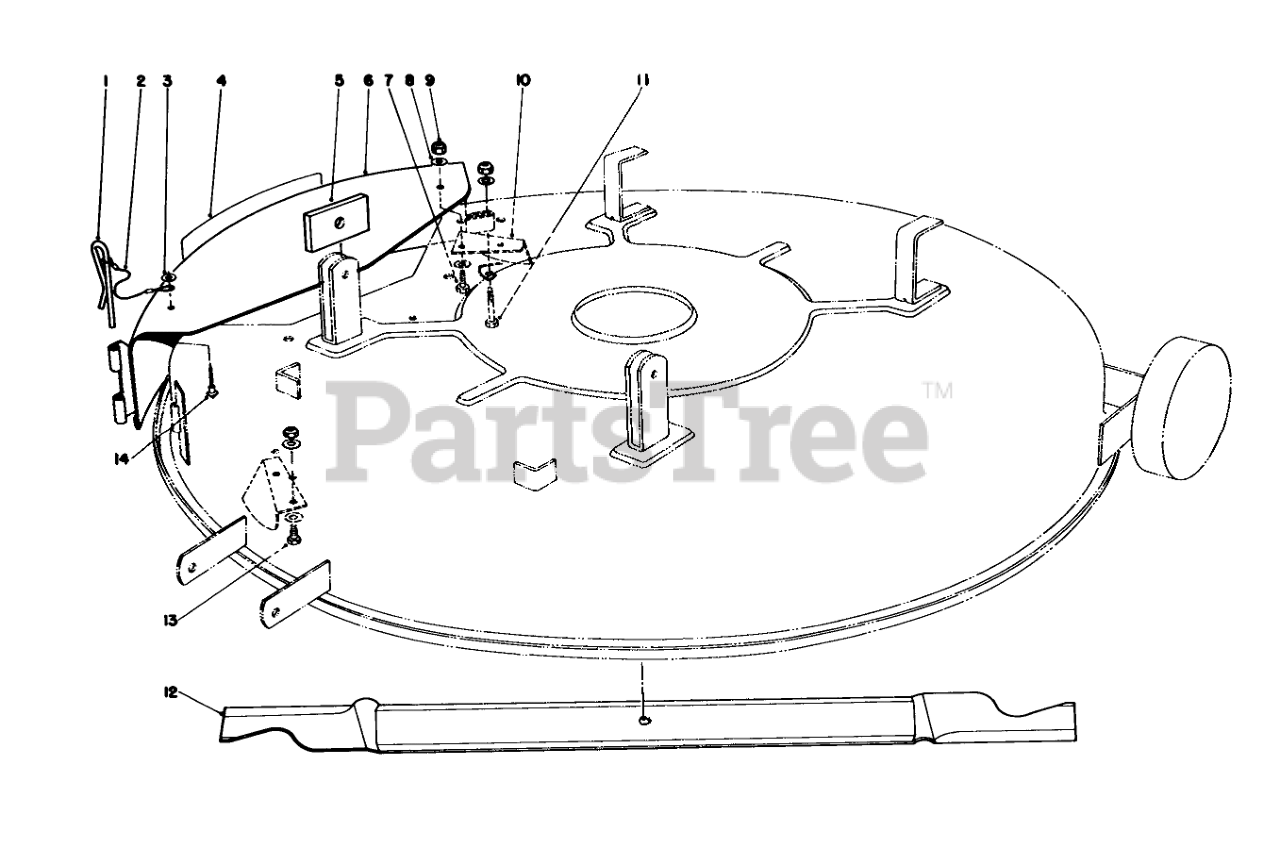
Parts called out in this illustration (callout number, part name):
1	PIN-LOCKING, CHUTE
2	8070 Lanyard
3	WASHER-PLAIN
4	COVER DECAL
5	SPACER
6	Cover-Mulcher Assembly (Incl. Ref. #1-4 8 14)
7	SCREW-HH
8	WASHER-PLAIN
9	NUT-LOCK, NI
10	KICKER B
11	SCREW-HH
12	Blade
13	SCREW-HH
14	RIVET-BLIND
